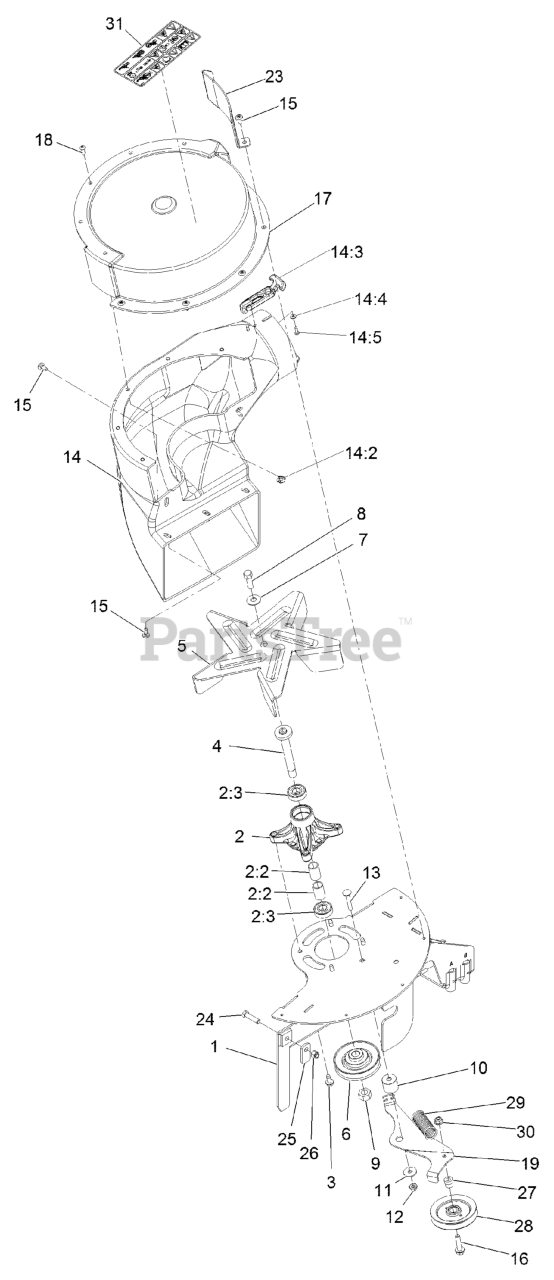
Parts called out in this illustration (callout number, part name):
1	WELDMENT-SUPPORT, BLOWER
2	SPINDLE ASM
2:3	BEARING-BALL
3	Screw-HWH 5/16-18 X 3/4 Tf
4	Shaft - Spindle
5	Fan-Blower
6	SHEAVE-BLOWER OFFSET
7	WASHER-BELLEVILLE
8	Screw-HH
9	Nut-Hex
10	SPACER-STEPPED
11	WASHER-PIVOT
12	NUT-HF, NI
13	SCREW-CARR
14	ASM-Blower Chute, Plastic
14:2	Insert-T-Nut
14:3	LATCH-RUBBER
14:4	WASHER-FLAT
14:5	SCREW-PPH
15	SCREW-SHOULDER
16	SCREW-HHF
17	ASM-BLOWER COVER
18	SCREW-PRH
19	ARM-IDLER, BLOWER
23	Guard-Blower
24	SCREW-HH
25	LATCH-CATCHER, GRASS
26	NUT-LOCK, NI
27	HUB,SPACER
29	SPRING-IDLER
30	NUT-HF, NI
31	DECAL-WARNING BLOWER W/RO
